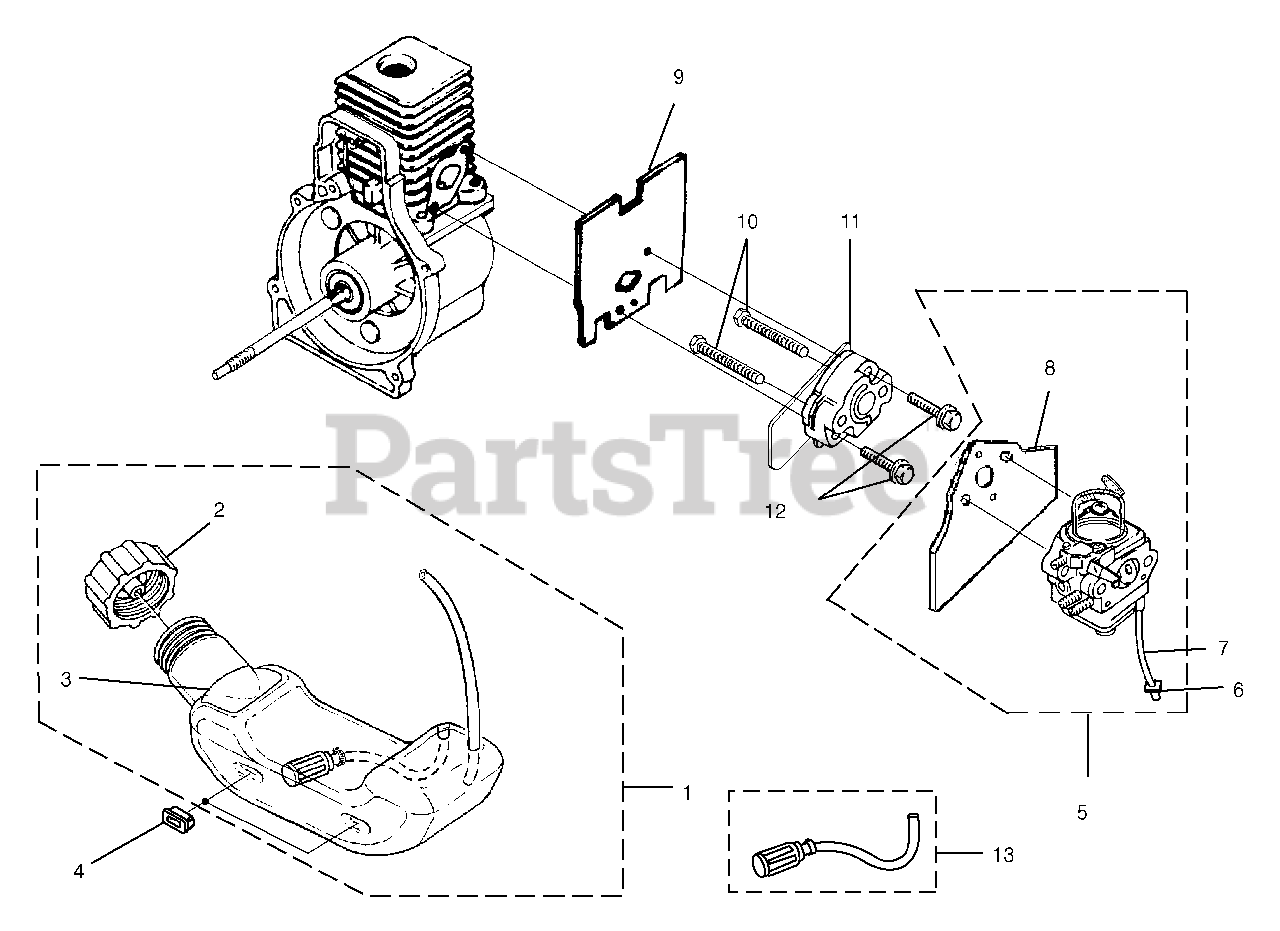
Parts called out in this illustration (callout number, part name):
1	FUEL TANK KIT
2	FUEL TANK CAP
3	HEAT SHIELD
4	RUBBER BUMPER
5	CARBURETOR KIT
6	INLINE FUEL FITTING
7	RUBBER TUBBING (3 in)
8	CARBURETOR GASKET
9	HEAT DAM GASKET
10	SCREW (10-24 x 2-1/4 in Hex Hd)
11	HEAT DAM
12	SCREW (10-24 x 1110 in pan Hd)
13	FUEL FILTER KIT
